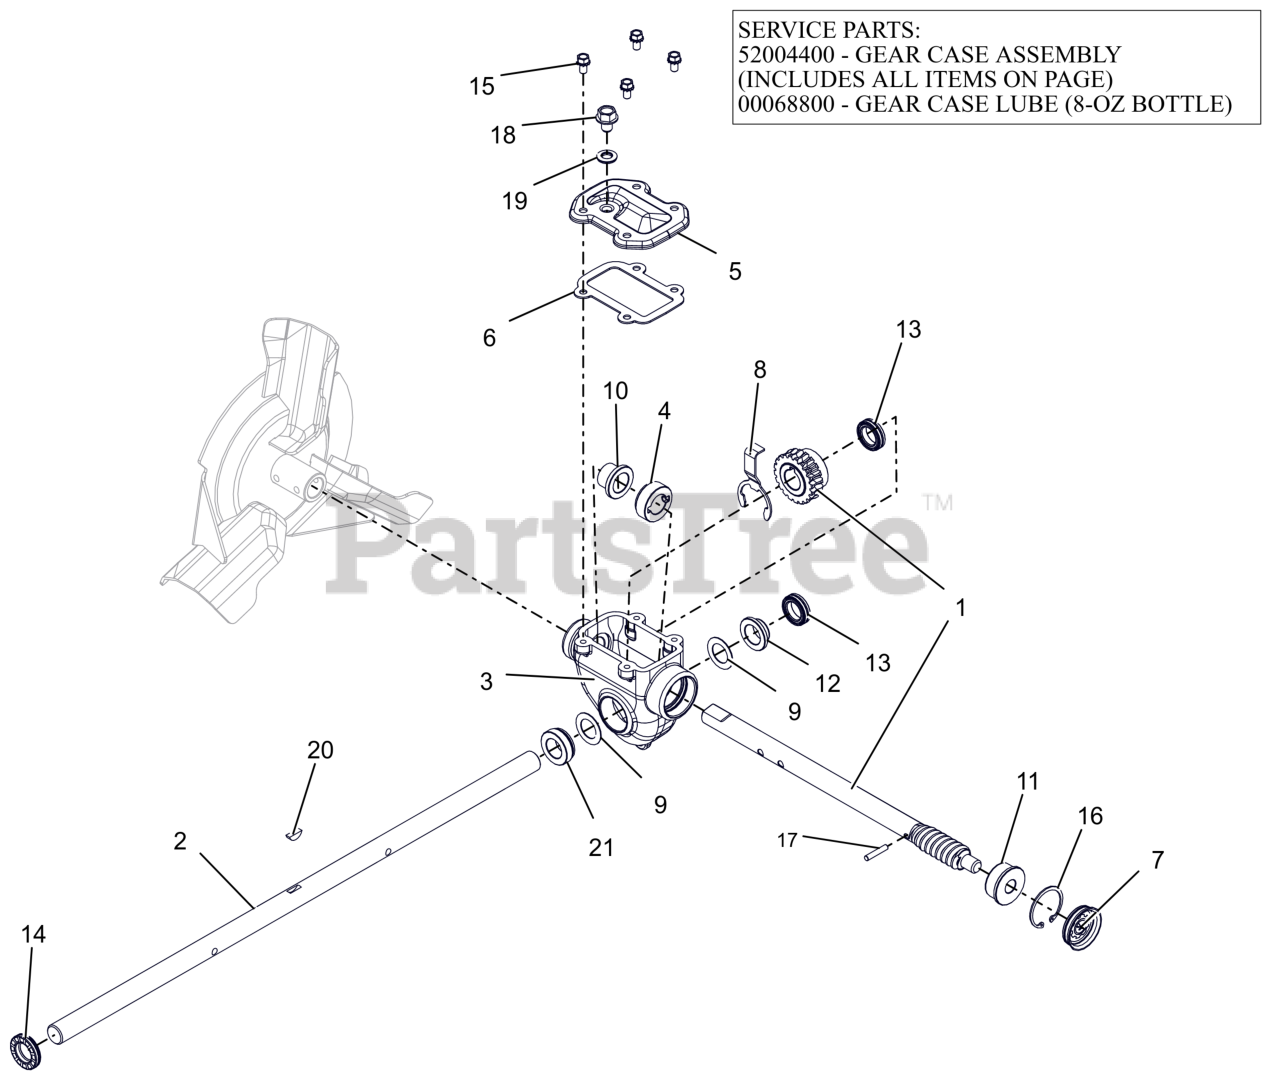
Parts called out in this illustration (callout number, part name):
1	SHAFT AND WORM GEAR ASSEMBLY
2	SHAFT, RAKE - 24" (.750 DIA)
3	GEARCASE, COMPACT MACHINED
3	GEAR CASE, 24" IRON SM TOP-LD
3	ARIENS L3 LUBE, 8 OZ BOTTLE
4	THRUST COLLAR, .75" ID SLIPFIT
5	COVER, TOP - COMPACT
6	GASKET, TOP - COMPACT GEARCASE
7	COVER, GEAR CASE 1.50"
8	BUSHING RETAINER, COMPACT
9	WSHR, FLT .760X1.225X.032 ZCC
10	BSHG-FLG .755X.878X.75X1.25
11	BSHG-FLG .503X1.303X.62X1.465
12	BSHG-FLG .755X.878X.424X1.25
13	SEAL-OIL .748X1.125X.312 TBC29
14	SEAL-OIL .748X1.300X.250 TBC29
15	BLT, SEMS .25-20X.50 G5 ZCC
16	RG-RTNG-INT 1.500X.050
17	PIN-STR .188X1.00 6150
18	SCR,TAP .38-15X.50 HWH ROLOK
19	WSHR-BND-SEAL .38X.75X.11 GALV
20	KEY-WDRF .19X.63 HRD #61
21	BSHG-FLG COMPACT, RIGHT
